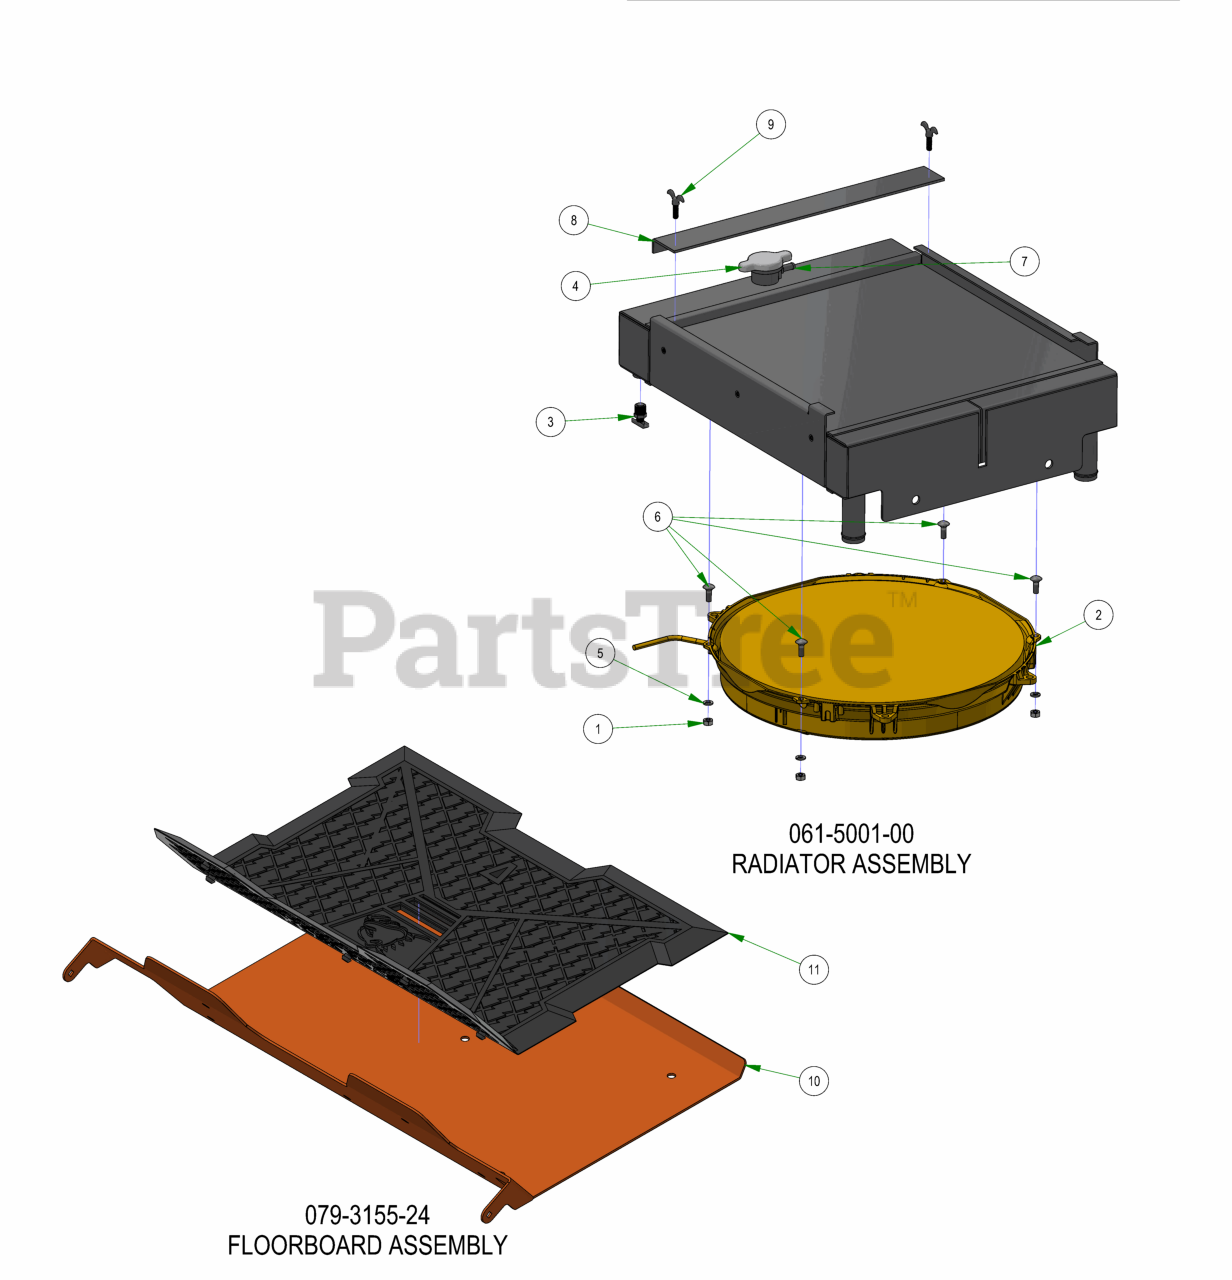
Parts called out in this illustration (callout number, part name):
1	1/4-20 HEX NUT ZINC
2	Electric Fan for 2019 Diesel Radiator
3	1/4 NPT Drain Plug
4	radiator cap
5	1/4SPLIT LOCKWASHER ZINC
6	1/4-20 X 3/4 CARRIAGE BOLT (GR.5) ZINC
7	1/4 Barb to 3/16 NPT Overflow Fitting
8	Screen Rentention Plate for 2019 Diesel Radiator
9	1/4-20 x 3/4 Thumb Screw
10	2024 R-Series Floorboard
11	2024 R-Series Floor Mat
